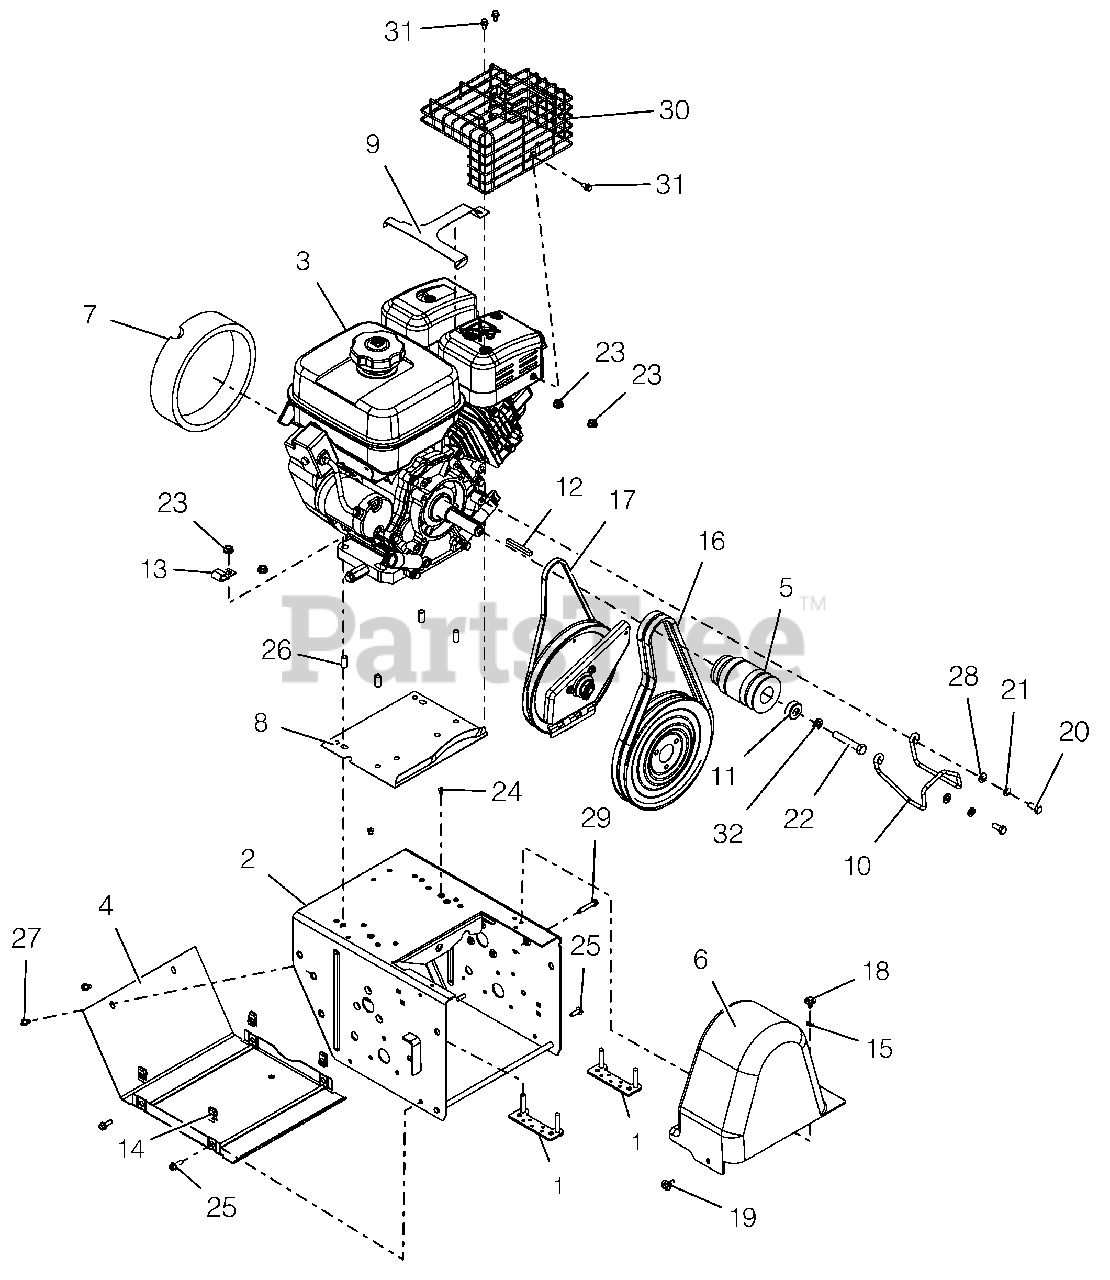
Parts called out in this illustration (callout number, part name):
1	STRAP, ENGINE BOLT-LARGE BRIGG
2	FRAME, MAIN - PRO (WELDMENT)
3	ENGINE,SUBARU EX27 AS 120V
4	COVER, BOTTOM
5	SHEAVE, SUBARU EX27
6	COVER, BELT-TALL PRO
7	FOAM COVER, RECOIL-SUBARU
8	BAFFLE, WATER - LARGE BLOCK
9	GUARD, SNOW-SUBARU
10	FINGER, BELT
11	BSHG-SPACER .47X1.25X.50
12	KEY .25X.25X2.25
14	NUT-RTNR .25-20X.56
15	NUT-PUSH .25X.50 O.D.
16	V-BELT, HA-RAW EDGE (SET)
17	V-BELT, 3L-RAW EDGE
18	SCR-TAP .25-20X.50 LGHWH TR YZ
19	SCR-TAP .25-20X.5 CAPTIVE
20	BLT-HEX .31-24X.75 YWZC GR5
21	WSHR-LK .312X.097 HVY YWZC
22	BLT-HEX .44-20X2.50 GR5 YWZC
23	@NUT-LK-CTR-FLG .31-18 YZ GR F
24	RVT-POP .187 YZ
25	BLT-HEX .25-20X.75 HWH YZ GR5
26	BSHG-SLV .325X.400X.795
27	SCR-TAP .25-20X.50 HWH TR YWZ
28	@WSHR-FL-STL.344X.688X.065YWZC
29	@SCR-TAP .25-20X1.50 HWH TR YZ
30	MUFFLER GUARD, SUBARU EX27
31	BLT-SERHFWH M6X1.0X12 8.8 CZ
32	@WSHR-LK .44X.109 REG YWZC
